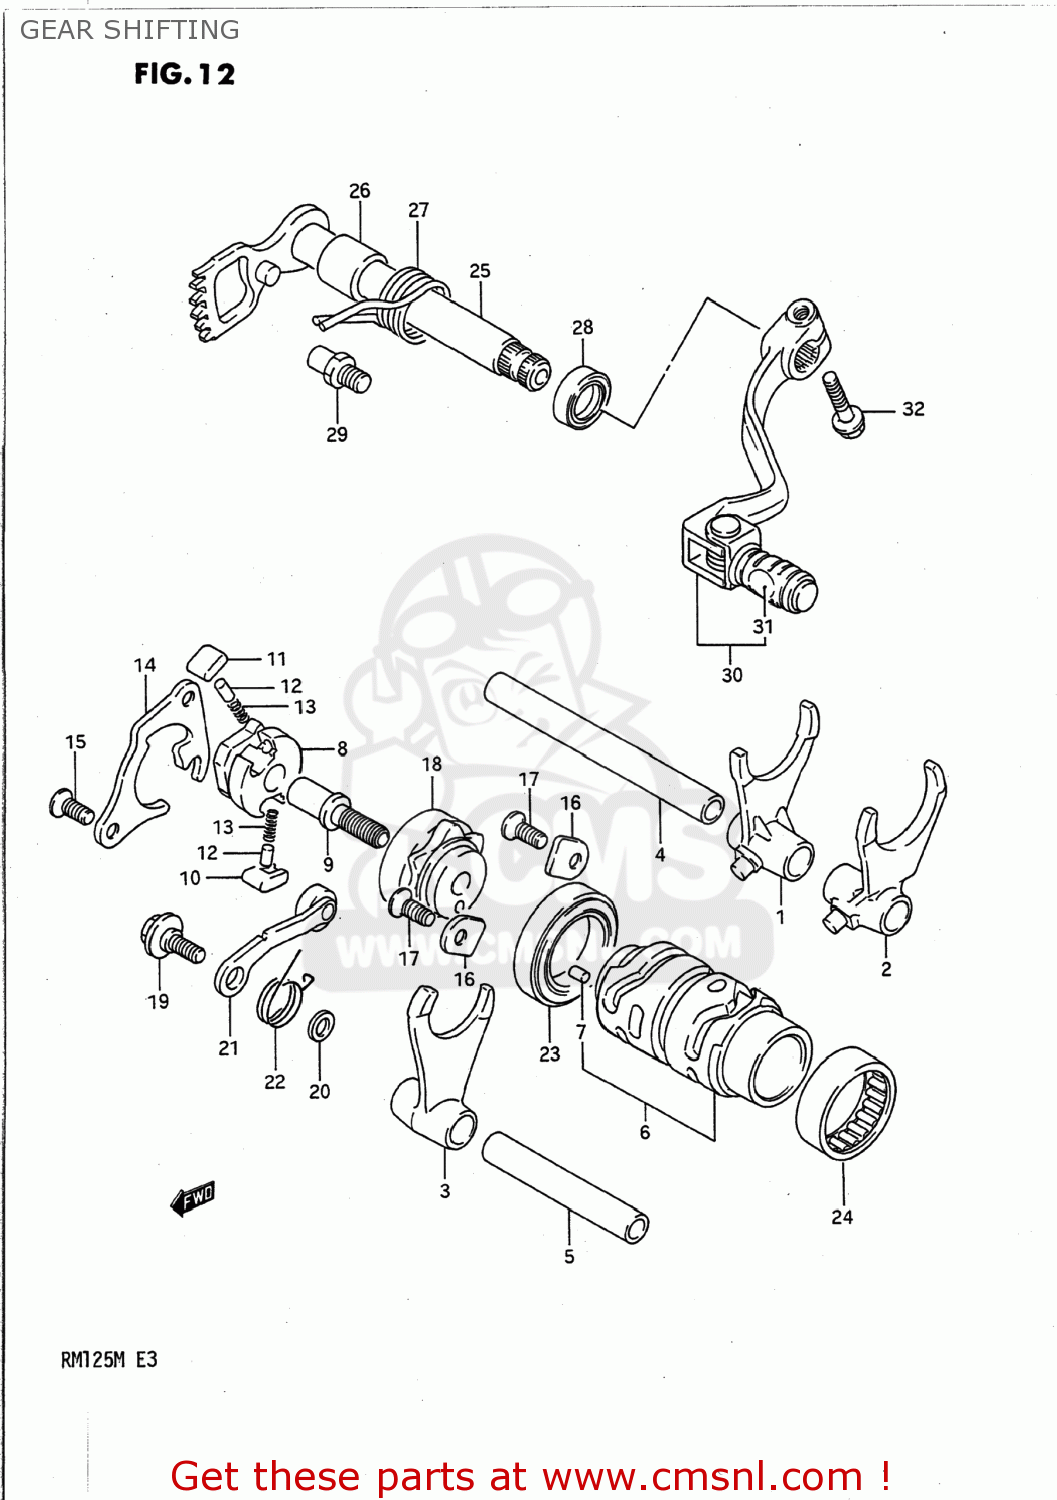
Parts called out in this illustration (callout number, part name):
1	FORK,GEAR SHIFT NO.1
2	FORK,GEAR SHIFT NO.2
3	FORK,GEAR SHIFT NO.3
4	SHAFT,GEAR SHIFT FORK
5	SHAFT,GEAR SHIFT FORK
6	CAM,GEAR SHIFT
7	PIN(4X11.8)
8	GEAR,GEARSHIFT CAM DRIVE
9	PIN,SHIFT CAM DRIVEN GEAR
10	PAWL,GEAR SHIFT NO.1
11	PAWL,GEAR SHIFT NO.2
12	PIN(5X8)
13	SPRING
14	LIFTER,GEAR SHIFT POLE
15	SCREW
16	RETAINER,COUNTER BEARING,R
17	SCREW
18	PLATE,GEAR SHIFT CAM STOPPER
19	BOLT(6X14.3)
20	WASHER
21	STOPPER,SHIFT CAM
22	SPRING
23	BEARING
24	BEARING(30X37X12)
25	SHAFT,GEAR SHIFT
26	SPACER(14X20X17.5)
27	SPRING
28	SEAL,OIL(14X22X7.3)
29	STOPPER,GEAR SHIFT CAM
30	LEVER ASSEMBLY,GEAR SHIFTING
31	RUBBER,GEAR SHIFT PEDAL
32	BOLT
